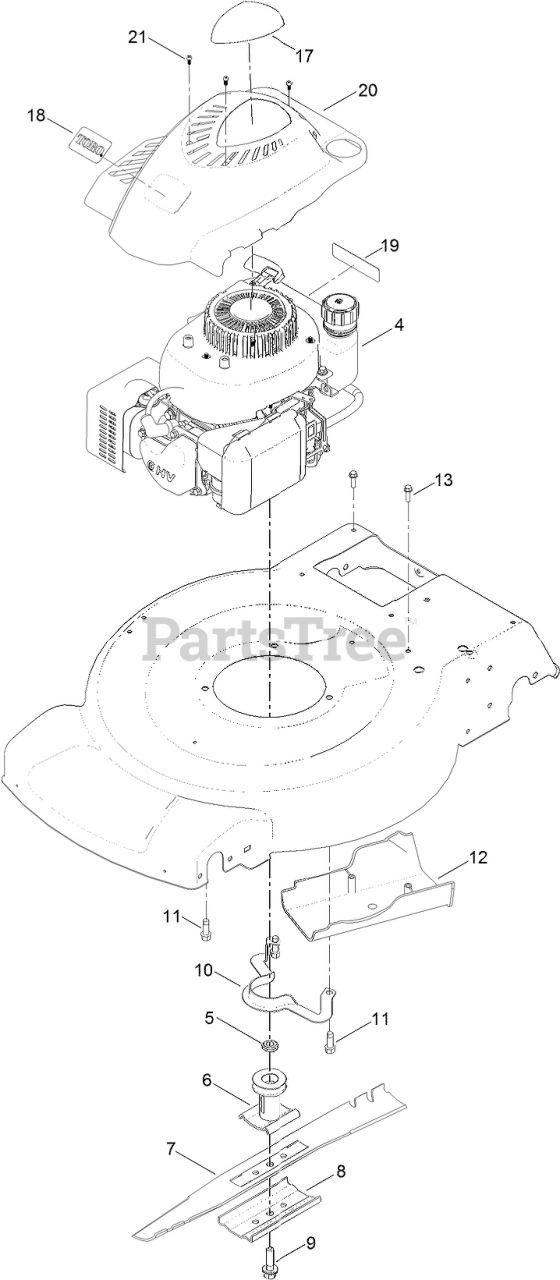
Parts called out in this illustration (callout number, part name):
4	ENGINE-1P65FC
5	Spacer-Driver
6	DRIVER-BLADE
7	BLADE-22 INCH
8	SUPPORT-BLADE
9	BOLT-BLADE
10	Guide-Belt
11	SCREW-TAPTITE
12	COVER-BELT
13	SCREW-HWH
17	DECAL-SHROUD
19	DECAL-ARRESTER, SPARK
20	SHROUD
21	SCREW-PPH
